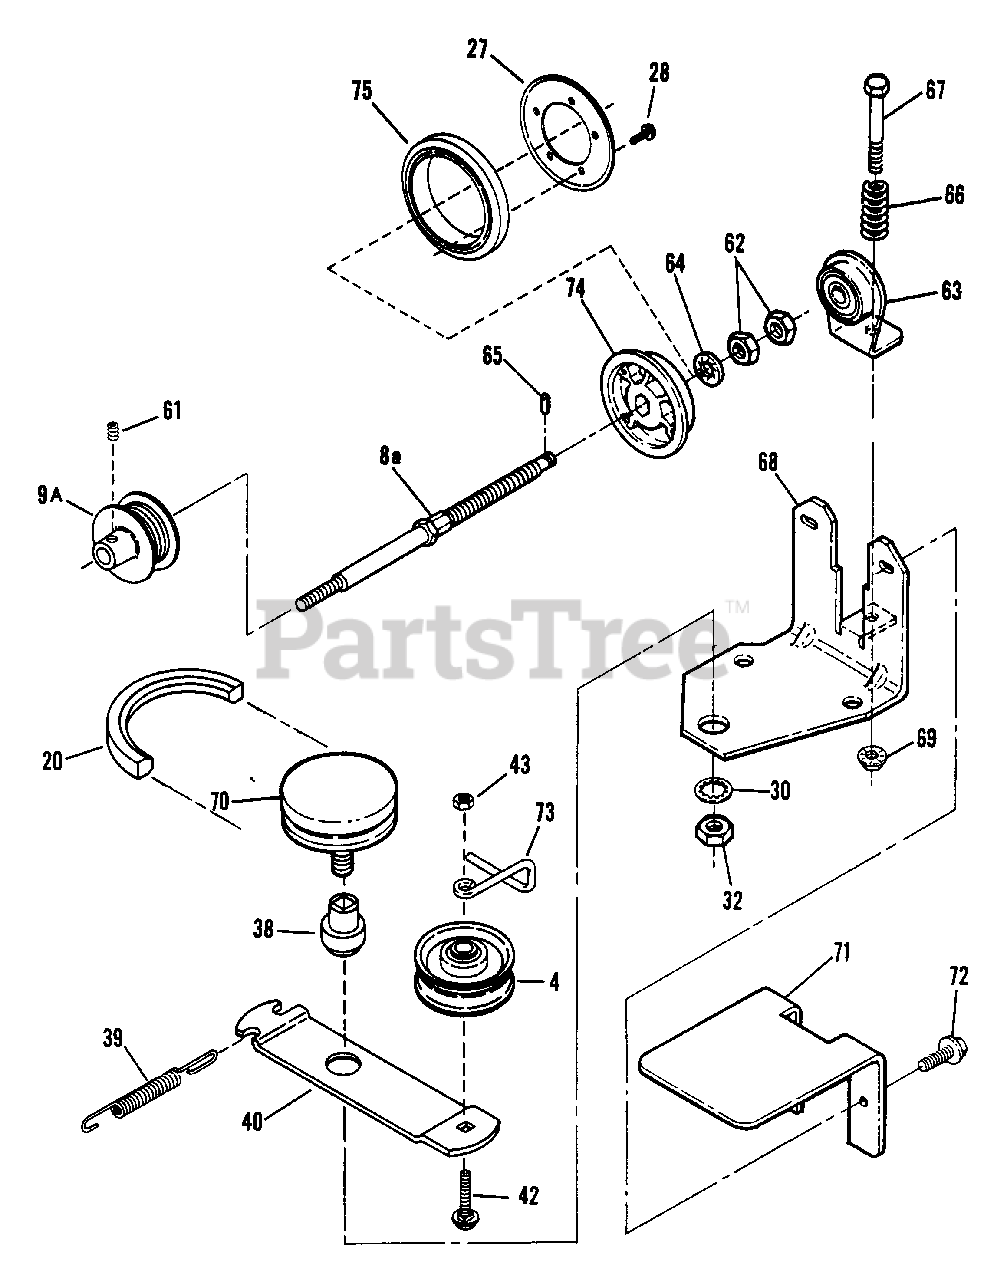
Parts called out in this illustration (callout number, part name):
4	PULLEY, Idler
8A	*SHAFT, Hex Drive
9A	*PULLEY, Poly V (1-3/4" O.D.)
20	BELT, Engine Drive
27	PLATE, Ring Retaining
28	SCREW, #10-24 x 1/2" Hex Washer Self-Tap (Torx)
30	WASHER, 3/8 Internal Tooth Lock
32	NUT, 3/8-24 Hex, Grade B
38	BUSHING
39	SPRING (Wheel Drive & Idler)
40	ARM, Idler
42	BOLT, 1/4-20 x 1-1/2" Carriage, Grade 5
43	NUT, 1/4-20 Hex Center Lock, Grade 5 or B
61	*SCREW, 1/4-28 x 1/4" Hex Socket Set
62	*NUT, 1/2-20 Hex, Grade 2
63	*ASSEMBLY, Holder & Bearing
64	*WASHER, 1/2 Internal Tooth Lock
65	*PIN, 1/8 x 3/4" Roll
66	*SPRING
67	*SCREW, 5/16-24 x 2-3/4" Hex Head Cap, Grade 5
68	*BRACKET, Deck
69	*NUT, 5/16-24 Hex Flange Top Lock
70	*ASSEMBLY, Drive Disk
71	*COVER, Driven Ring
72	*SCREW, #10-24 x 1/2" Hex Washer Self-Tap (Torx)
73	*SCRAPER, Drive Pulley
74	*HUB, Driven Disc
75	*RING, Driven
